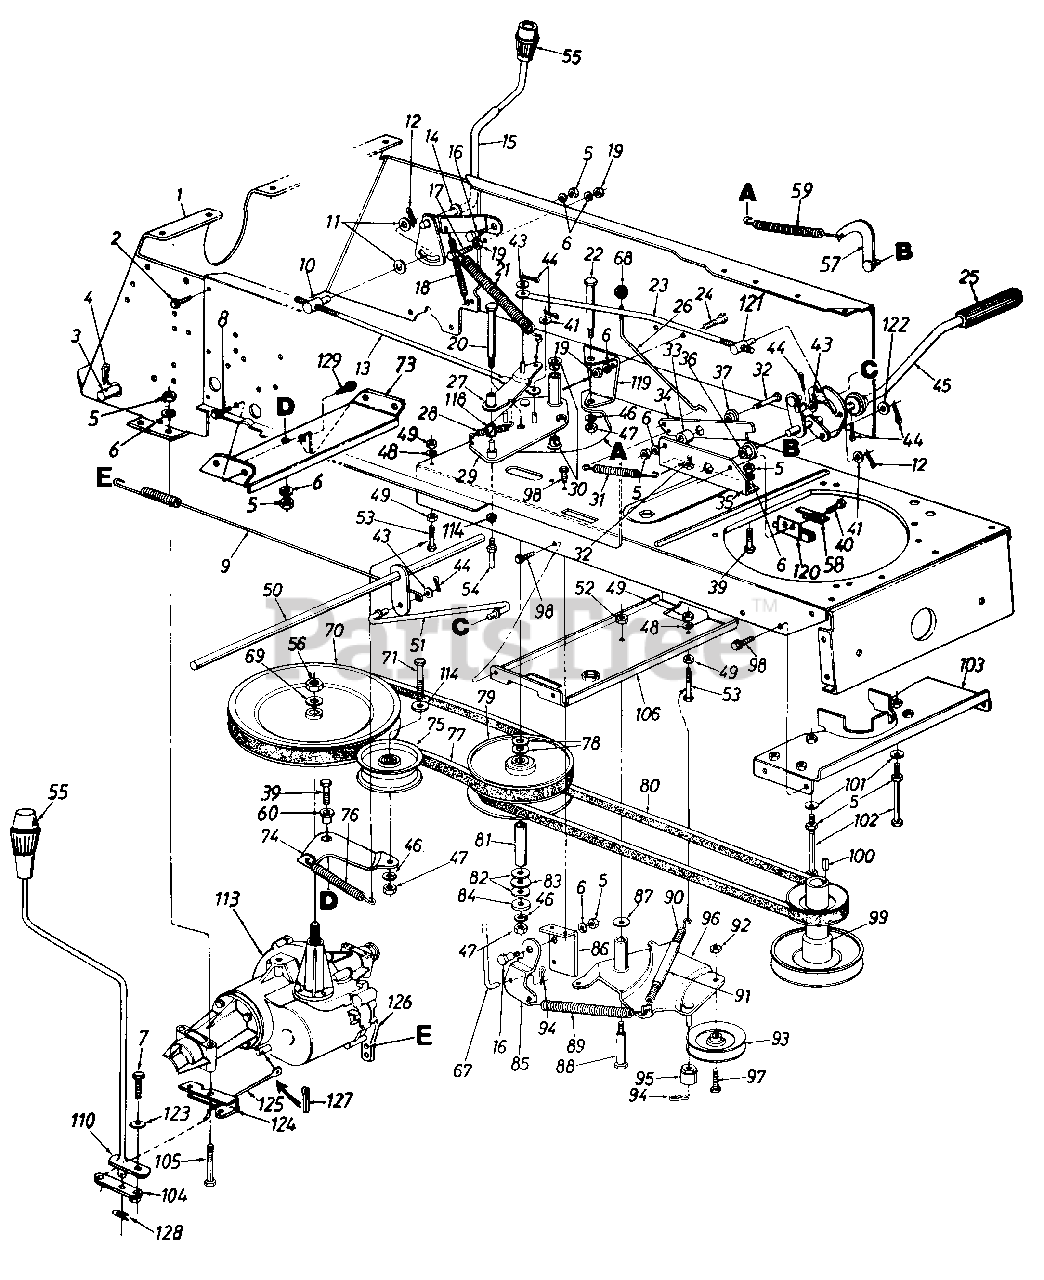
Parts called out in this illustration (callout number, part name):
1	Hitch Plate
2	Hex AB-Tap Scr. 5/16" x .75"
3	Hitch Rod
4	Hitch Pin Clip
5	Hex Nut 5/16-18 Thd.*
6	L-Wash. 5/16" I.D.*
7	Hex Bolt 1/4-28 x .62" Lg.
8	Hex Wash. Hd. TT-Tap Scr. 5/16-18 x .62" Lg.
9	Brake Extension Spring
10	Adjustment Ferrule 3/8-24 Thd.
11	Fl-Wash. .385" I.D. x .87"
12	Internal Cotter Pin
13	Speed Control Link
14	Fl-Wash. .531" I.D. x .94"
15	Speed Selector Lever Ass'y.
16	Shld. Bolt .437" Dia. x .162"
17	Hex Bolt 5/16-24 x 1.25" Lg.
18	Extension Spring 3.9" Lg.
19	Hex Nut 5/16-24 Thd. (Grade 5)
20	Hex Bolt 3/8-24 x 4.5" Lg.
21	Extension Spring 11" Lg.
22	Shld. Bolt .625" Dia. x 3.5" Lg.
23	Speed Control Link
24	Hex Bolt 5/16-24 x .75" Lg.
25	Foot Pad
26	Parking Brake Link
29	Pulley Plate Ass'y.
30	Flanged Brg. .630" I.D.
31	Extension Spring 2.51" Lg.
32	Hex Bolt 5/16-18 x 1.25" Lg.*
33	Spacer .34" I.D. x .88"
36	Hex Flange Brg. .634" I.D.
37	Shld. Spacer .5" Dia.
39	Hex Bolt 5/16-18 x .751' Lg.*
40	Hex Tap Scr. #10-32 x 5/8 Lg.
41	Fl-Wash. .406" I.D. x .75" O.D.
43	Fl-Wash. .34" I.D. x .68" O.D.
44	Cotter Pin 3132" Dia.
47	Hex Nut 3/8-24 Thd.
48	L-Wash. 1/4" I.D.*
49	Hex Nut 1/4-20 Thd.*
50	Brake Link Bracket
51	Front Brake Rod Link
52	Hex Cent. L-Nut 3/8-16 Thd.
53	Hex Bolt 1/4-20 x 2.0" Lg.
54	Belt Guard Pin
55	Shift Knob
56	Hex Jam Nut 9/16-18 Thd.
57	Foot Pedal Brkt. Ass'y.
58	Switch Plate
59	Ext. Spring 5.2" Lg.
60	Shld. Spacer .3/8" I.D. x 1.125"
67	Deck Control Rod
68	Ball Knob Brake
69	Bell-Wash. 9116" I.D. x 1.25"
70	V-Pulley 9-1/4' O.D.
71	Hex Bolt 3/8-24 x 1.75" Lg.
75	Flat Idler 3.5" O.D.
76	Extension Spring 6.12" Lg.
77	V-Belt
78	Teflon Washer 1.20" O.D.
79	Variable Speed Pulley 6" Dia.
80	V-Belt
81	Pivot Bushing
82	Fl-Wash. .56" I.D. x 1.0" O.D.
83	Thrust Brg. .56" I.D. x 1.25"
84	Retainer Cup
85	Deck Control Pivot Brkt.
86	Parking Brake Mtg. Brkt.
87	Bell-Wash. .38" I.D. x .88" O.D.
88	Shld. Bolt .498" Dia. x 2.05"
89	Extension Spring 6.12" Lg.
90	Extension Spring 6.37" Lg.
91	Convoluted Conduit 4" Lg.
92	Hex Cent. L-Nut 3/8-24 Thd.
93	V-Belt Idler
94	Internal Cotter Pin
95	Spacer
96	Idler Brkt. Deck Ass'y.
97	Hex Bolt 3/8-24 x 1.5" Lg.
98	Hex TT-Tap Scr. 1/4-20 x 5n
99	Engine Pulley
100	Sq. Key 1/4 x 1.5" Lg.
101	Bell-Wash. .345" I.D. x .88"
102	Hex Bolt 5/16-18 x 5.25" Lg.
103	Belt Keeper Brkt. Ass'y.
104	Shift Lever Link Ass'y.
105	Hex Bolt 5/16-18 x 3.25" Lg.
106	Deck Idler Support Brkt.
110	Shift Lever Ass'y.
113	Transmission Comp.
114	Fl-Wash. 3/8" I.D. x 1.0" O.D.
118	Nyliner Flanged Brg.
119	Variable Speed Support Brkt.
120	Safety Switch
121	Adjustment Ferrule 3/8-24 Thd.
122	Fl-Wash. .344" I.D. x .62" O.D.
123	Bell-Wash. .265" I.D. x .75" O.D.
124	Shift Lever Support Brkt.
125	Shift Lever Rod
126	Actuating Arm
127	Cotter Pin 3/4" Lg.
128	Internal Cotter Pin
129	Hex Wash. Hd. TT-Tap Scr. 5/16-18 x 1.75" Lg.
